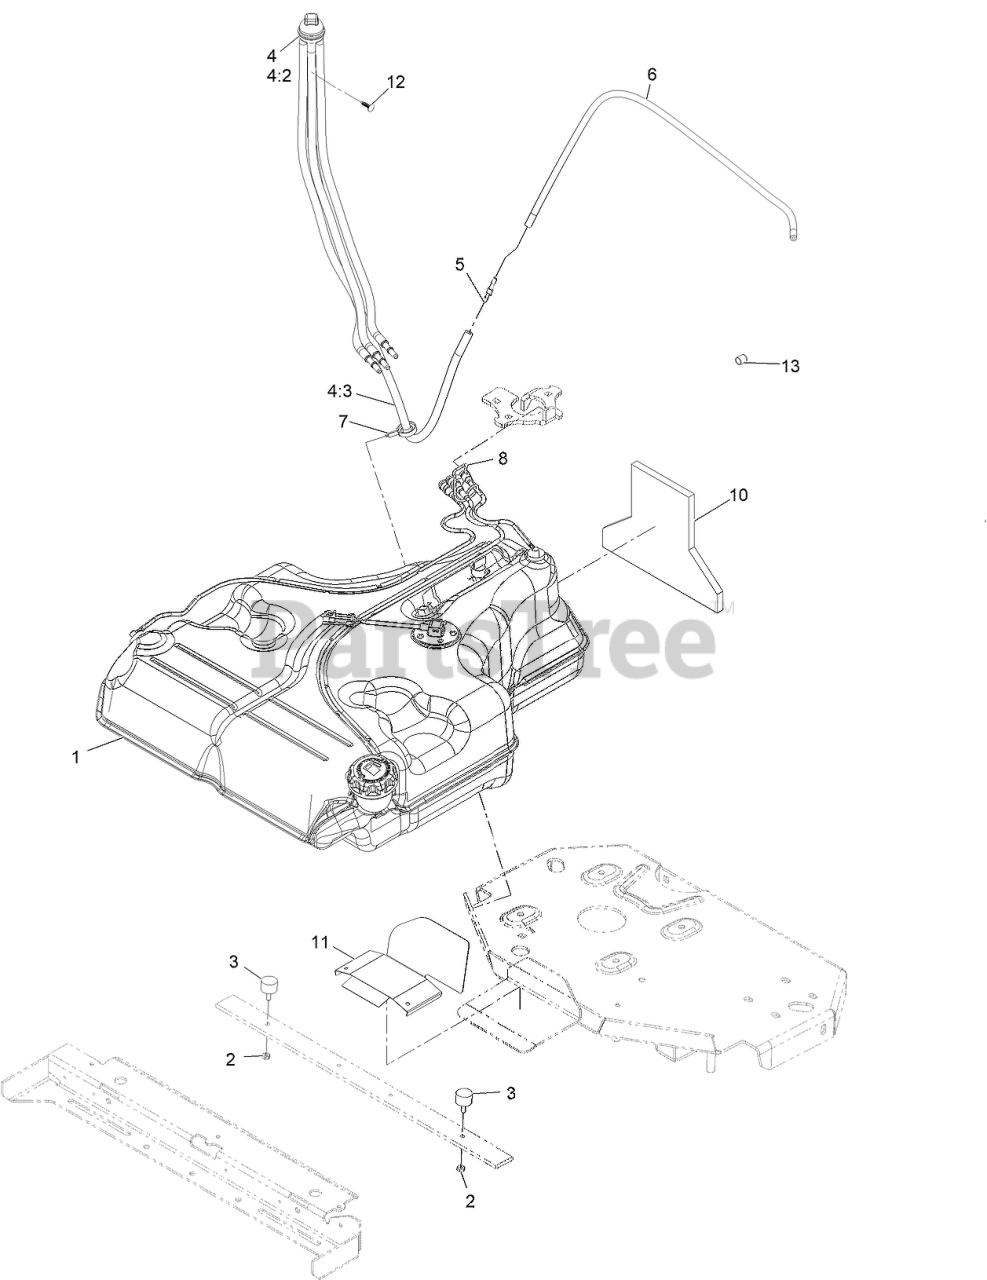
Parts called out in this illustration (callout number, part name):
1	FUEL TANK ASM
2	NUT-JAM
4	FUEL MANIFOLD VENT ASM
4:2	HOSE-FUEL
4:3	HOSE-FUEL
5	BARB-FUEL
6	HOSE-FUEL
7	CLAMP-HOSE
8	RETAINER-LINE, VAPOR
10	INSULATION-FOAM, FUEL TANK
11	GUARD-EXHAUST
12	PLUG-PLASTIC
13	PLUG-PORT
